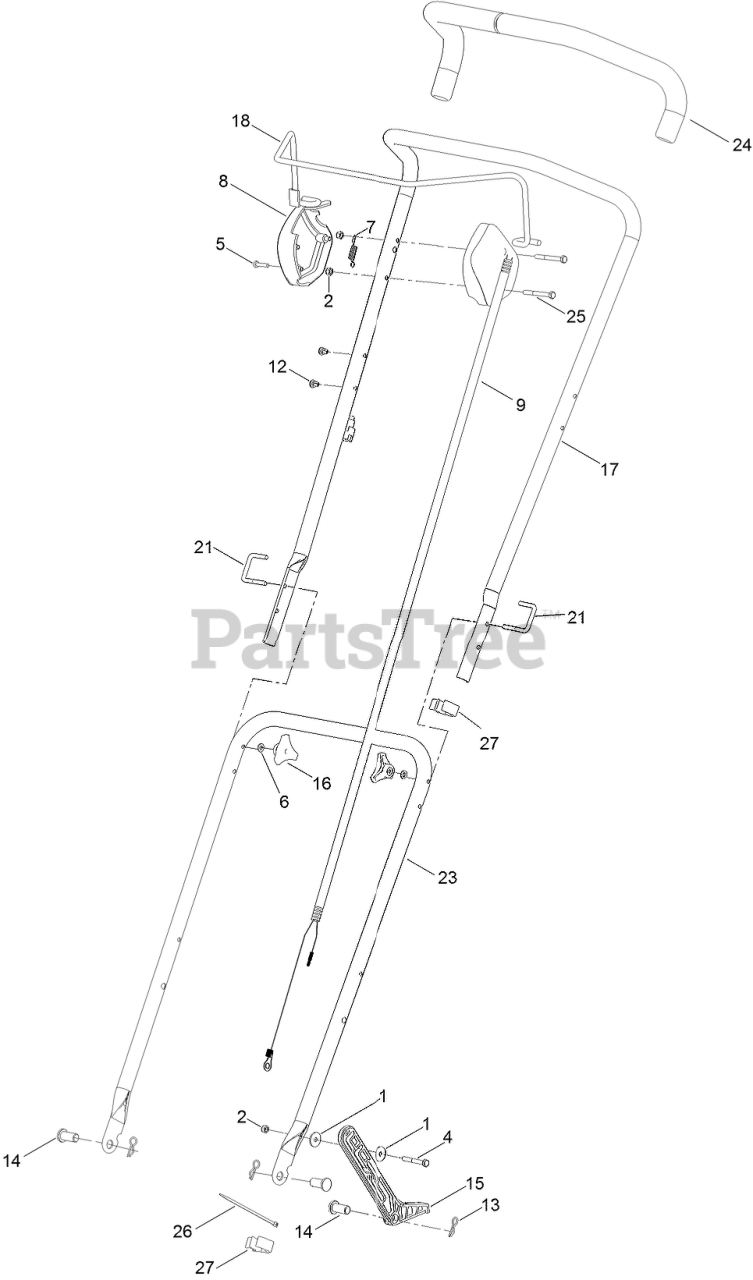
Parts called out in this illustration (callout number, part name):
1	WASHER
2	NUT-NYLOC
4	BOLT-HH
5	SCREW-PLASTITE
6	WASHER-PLAIN
7	SPRING-RETURN
8	BOX-SWITCH, LH
9	OPC WIRE LOOM ASM
12	FASTENER-DRIVE
13	CLIP-R
14	PIN-RETAINING
15	FOOTSTOP
16	HANDWHEEL
17	HANDLE-UPPER
18	ARM-BAIL
21	BOLT-U
23	HANDLE-LOWER
24	GRIP-HANDLE
25	BOLT-HEX
26	TIE-CABLE
27	GUIDE-CABLE
